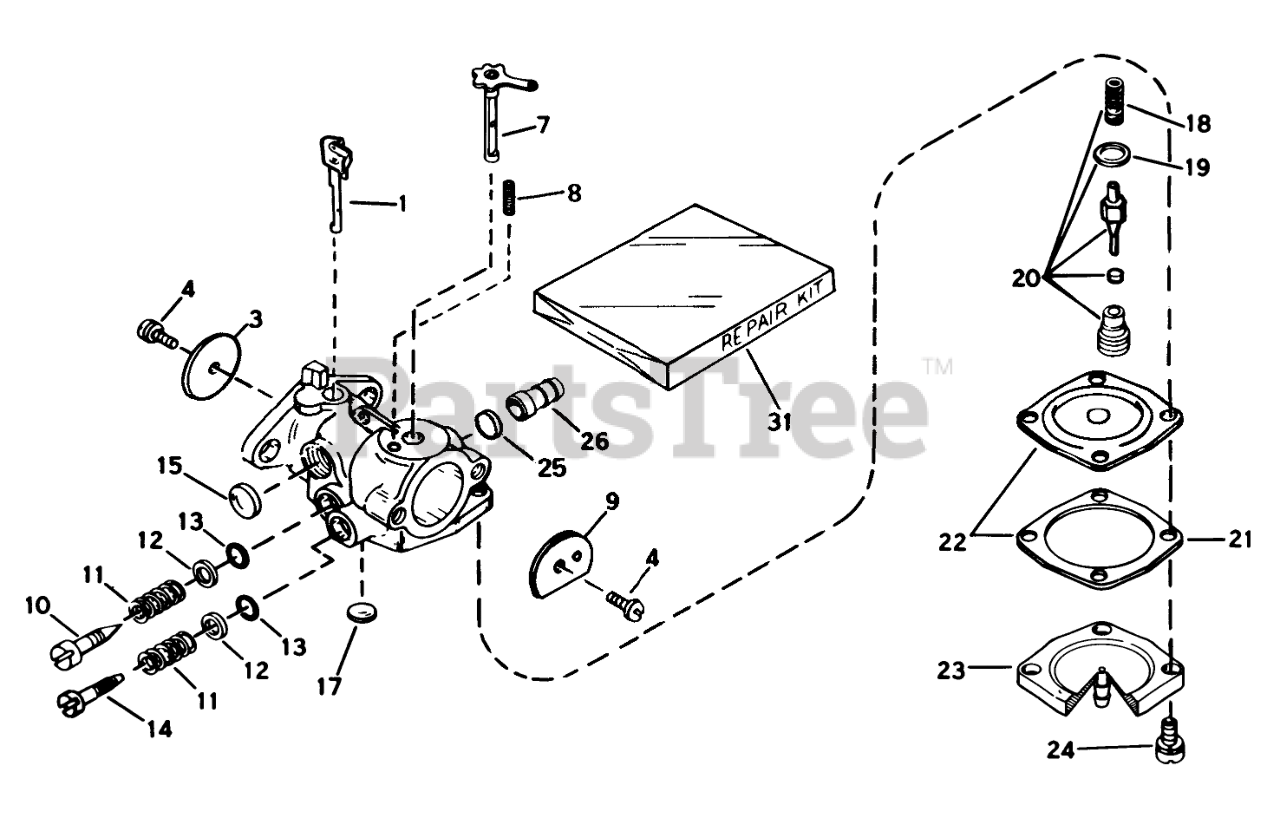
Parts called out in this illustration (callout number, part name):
1	Shaft/Lever-Throttle
3	Shutter-Throttle
4	Screw-Shutter
7	Shaft & Lever Assembly
8	Spring-Positioning, Choke
9	Shutter-Choke
10	Screw-Idle Adjustment
13	"O"Ring
14	Screw Main Adjustment
15	Plug-Welch, Idle Mixture Well
17	Plug Welch
18	Spring-Valve
19	Gasket-Valve Seat
20	Inlet Needle, Seat, Spring & Gasket Assy.(Incl. #18 & 19)
21	Gasket-Diaphragm
22	Diaphragm Assy. (Incl. #21)
23	Cover-Diaphragm
26	Fitting-Fuel
31	Kit-Repair
